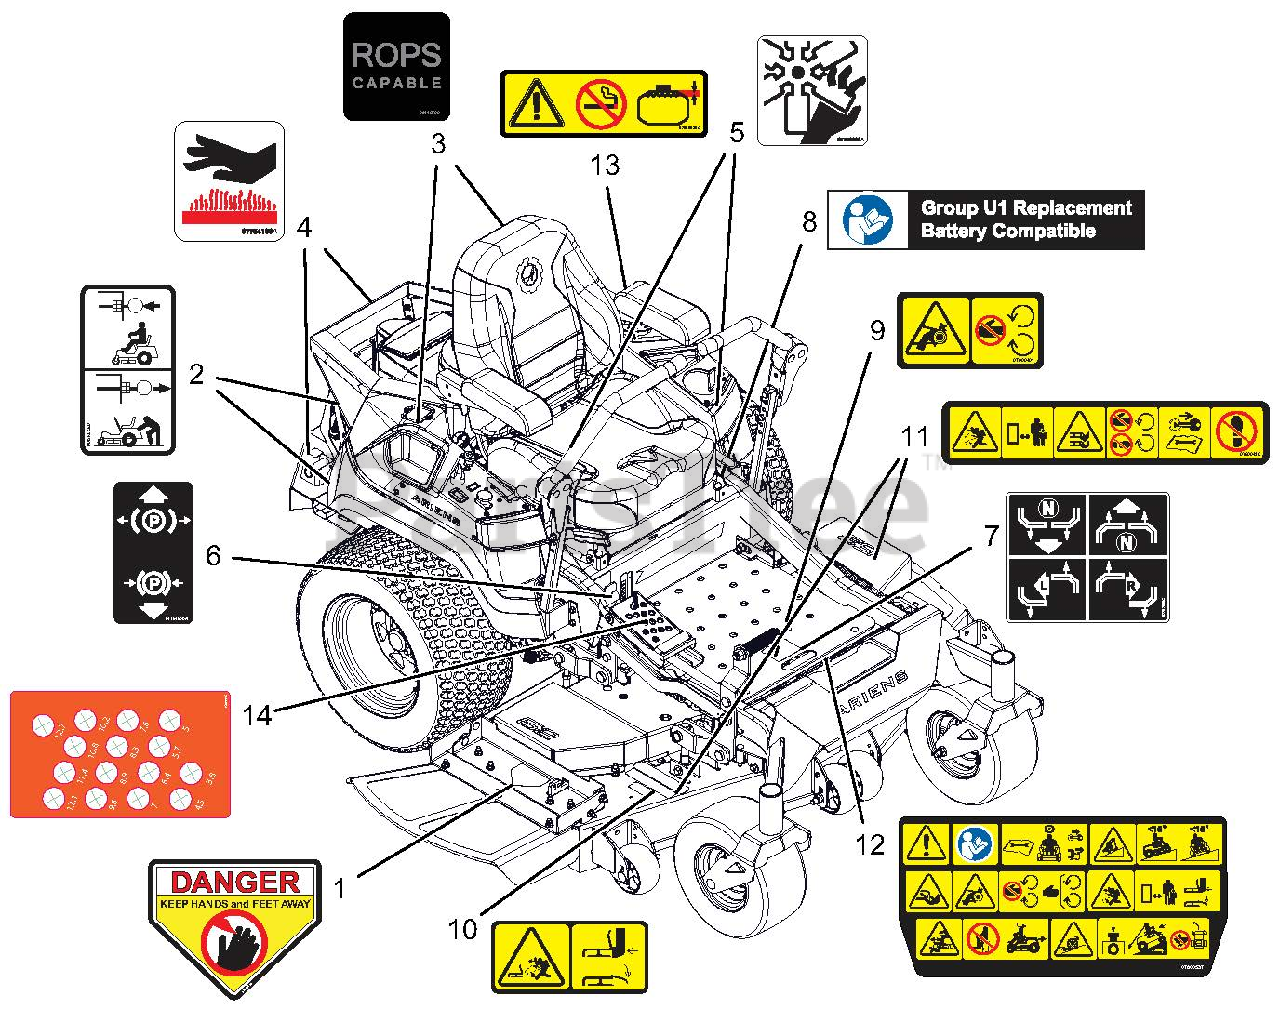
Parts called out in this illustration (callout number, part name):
1	DECAL, DANGER
2	DECAL, TRANSMISSION DISCONNECT
3	DECAL, ROPS LOCATION
4	DECAL, HOT SURFACE
5	DECAL, DANGER FAN
6	DECAL, PARKING BRAKE LEVER
7	DECAL, INSTRUCTIONAL-STEERING
8	DECAL, U1 BATTERY REPLACEMENT
9	DECAL, SAFETY - GUARDING
10	DECAL, SAFETY - DECK GUARDING
11	DECAL, DECK SAFETY
12	DECAL, MAIN SAFETY
13	DECAL, FUEL WARNING
14	DECAL, APEX HOC METRIC
